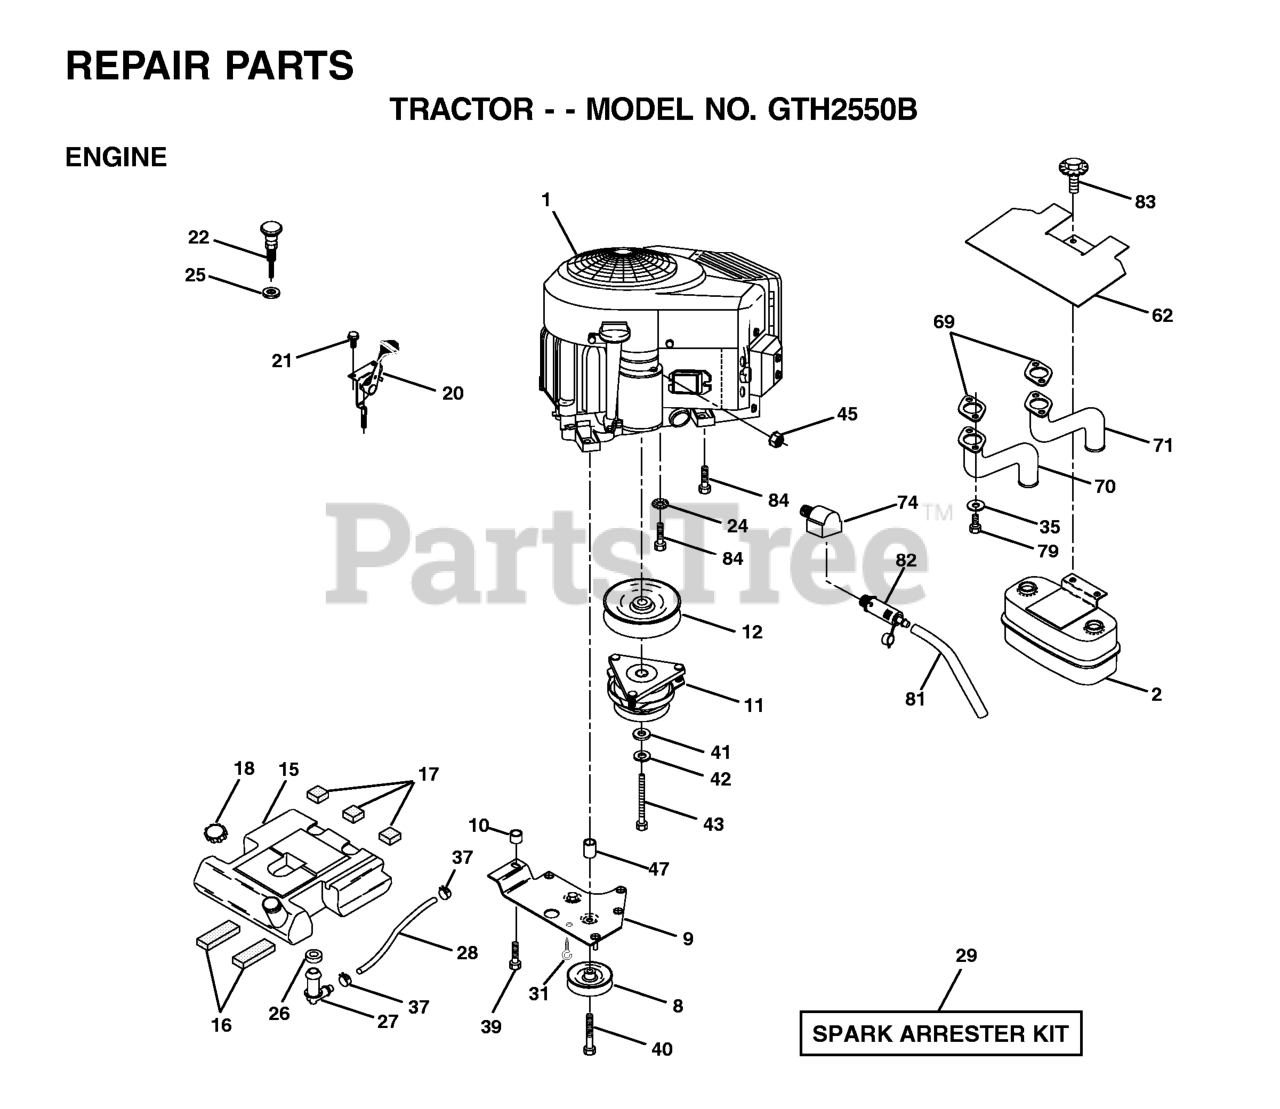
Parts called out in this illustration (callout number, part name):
2	MUFFLER.TWIN.CYL.LOW.TONE
8	RP.IDLER GROOVED
9	KEEPER ASM BELT ENGINE
12	PULLEY ENG VGT ELECT CLUTCH
15	FUEL TANK 3.5G
16	PAD IDLER TI
17	PAD-SPACER LT
18	CAP, FUEL GUAGE
20	THROTTLE CABLE
21	SCREW
22	REPL BY 532 1754-40
24	LOCKWASHER
25	Nut Keps 3/8 - 24 UNF
26	BUSHING OUTLET T
27	STEM FUEL TANK
28	FUEL LINE
29	KIT.SPARK ARRESTOR 794945 B&S
35	WASHER.LOCK.HVY.HLCL.SPR.5/16
37	HOSE CLAMP
39	SCREW TT 3/8-16X2-1/4 UNC
40	Screw TT 3/8-16 x 4 unc
42	LOCKWASHER
43	BOLT HEX 7/16-20X4-1/4"
45	NUT
62	RP SHIELD HEAT MUFFLER
69	GASKET.MUFFLER
70	TUBE.EXHAUST.B&S.VGT.LH
71	TUBE.EXHAUST.B&S.VGT.RH
74	ELBOW STREET BRASS
79	SCREW
81	TUBE, DRAIN OIL ASM.
82	PLUG, OIL DRAIN EASY
83	BOLT.5/16-18UNCX3/4 W/SEMS.BLK
84	SCREW 3/8-16 X 1-1/2
